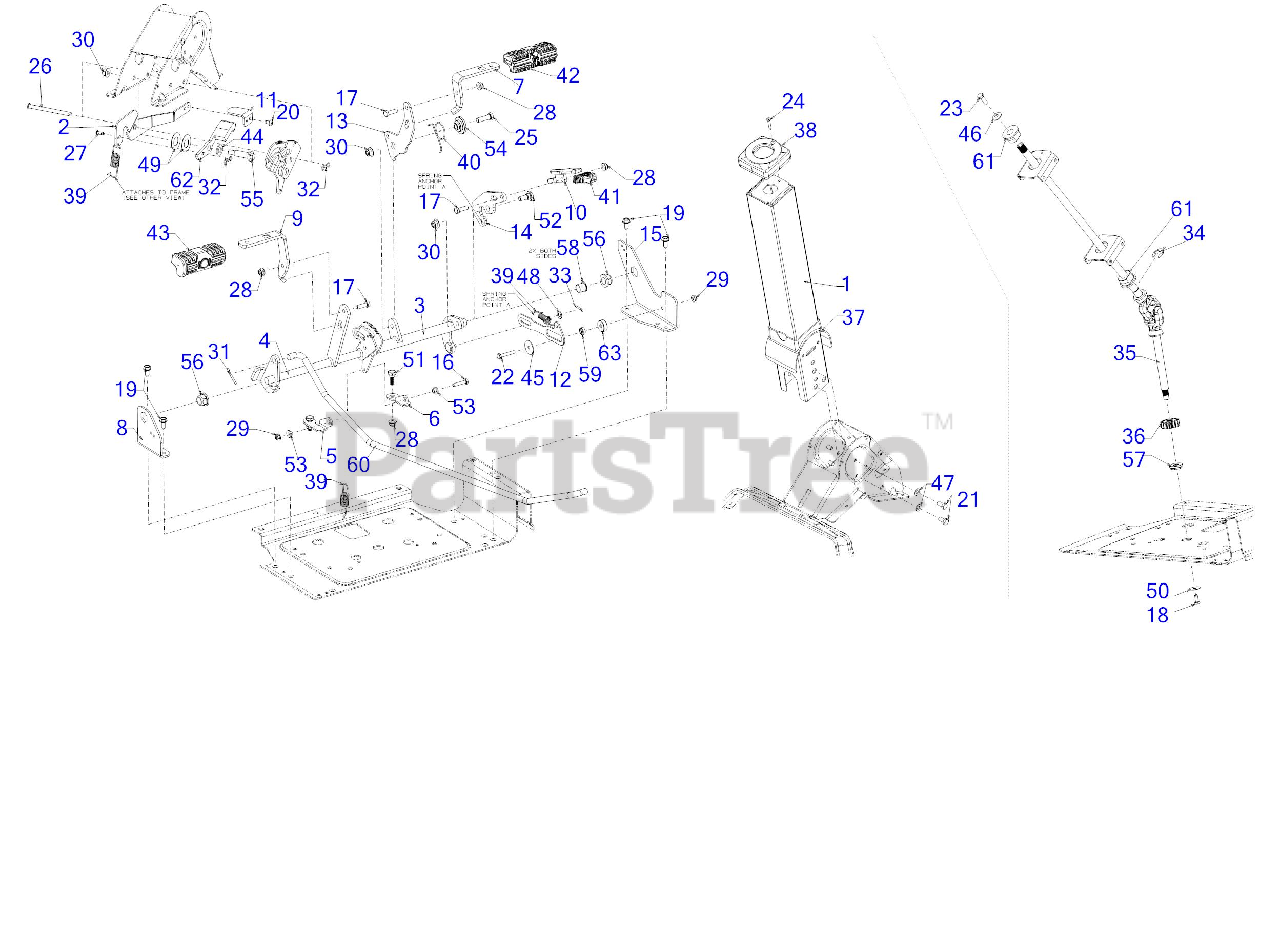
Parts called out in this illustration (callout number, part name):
1	STEERING COLUMN ASSEMBLY
2	CRUISE/BRAKE ARM
3	FORWARD PEDAL SHAFT ASSEMBLY
4	BRAKE SHAFT ASSEMBLY
5	PEDAL SHAFT BRACKET (LH)
6	PEDAL SHAFT BRACKET (RH)
7	FORWARD DRIVE PEDAL
8	BEARING SUPPORT BRACKET
10	REVERSE DRIVE PEDAL
11	TILT STEERING PEDAL
12	NEUTRAL RETURN LINK
13	FORWARD PEDAL BRACKET
14	REVERSE PEDAL PIVOT PLATE
15	PEDAL BEARING BRACKET (RH)
16	HEX SCREW 1/4-20 x 1.25
17	SCREW 5/16-18 x 1.0 GR5
18	SCREW 1/4-20 x .62 SPEC GR5
19	SCREW 5/16-18 x .750
20	SCREW 1/4-20 x .5
21	SCREW 5/16-18 x .62 GR5
22	SCREW 1/4-20 x 1.50 GR.5
23	SCREW 5/16-24 x .875 GR5
24	SCREW #10-16 x 1.25
25	SCREW 3/8-16 x 1.25 GR5
26	CLEVIS PIN 5/16 x 4.135
27	CLEVIS PIN .224 x .625
28	FLANGE LOCK NUT 5/16-18
29	FLANGE LOCK NUT
31	COTTER PIN-5/32 DIA
32	BOW TIE COTTER PIN 1/4-5/16
33	COTTER PIN
34	E-RING
35	STEERING SHAFT ASSEMBLY
36	STEERING GEAR 14T
37	COLUMN TOWER COVER
38	STEERING COLUMN COVER
39	EXTENSION SPRING
40	TORSION SPRING
41	REVERSE PEDAL PAD
42	FORWARD PEDAL PAD
43	BRAKE PEDAL PAD
44	FLAT WASHER .535 x .930 x .090
45	FLAT WASHER
46	BELL WASHER .337 X.867 x .057
47	FLAT WASHER
48	WASHER THRUST .375X.70X.030
49	THRUST WASHER
50	FLAT WASHER
51	SHOULDER SCREW .437
52	SHOULDER SCREW
53	SHOULDER SPACER
54	SHOULDER SPACER 1.50X.38X.38
55	SHOULDER SCREW .496X1.44 3/8-16
56	FLANGE BEARING
57	HEX FLANGE BEARING 7/16
58	NYLINER BEARING
59	BALL BEARING .25 X .625
60	FRONT BRAKE ROD
61	FLANGE BEARING
62	CRUISE LATCH
63	SPACER .267X1.00X.36
